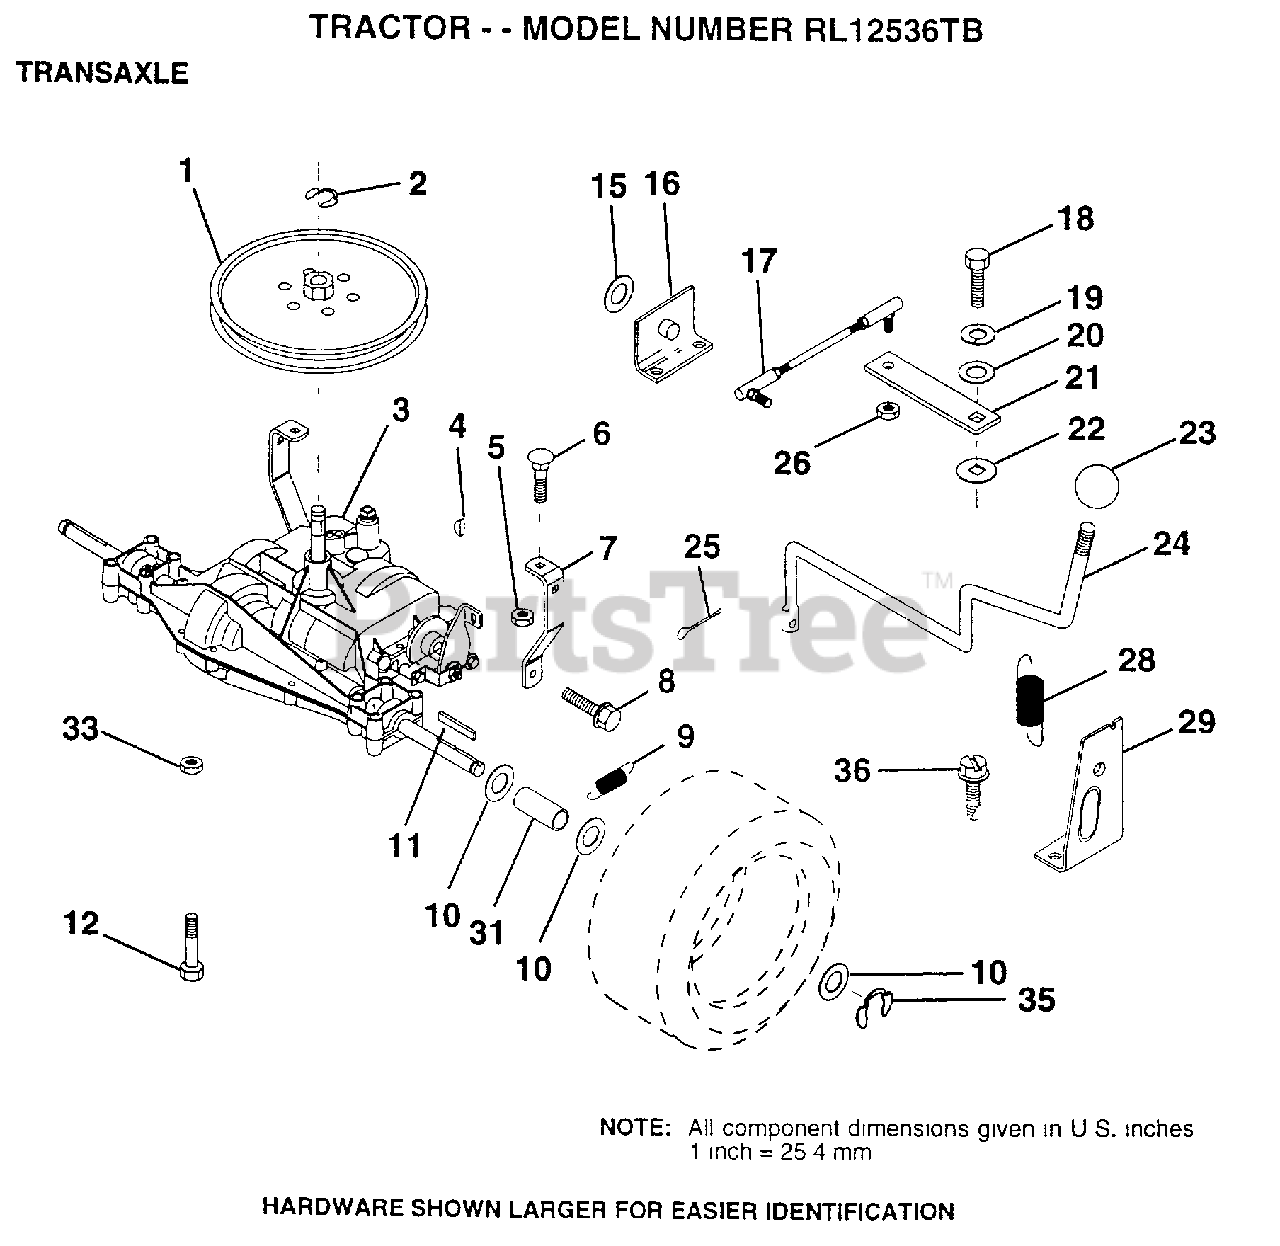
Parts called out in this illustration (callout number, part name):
1	PULLEY
6	BOLT
7	"STRAP,TORQUE"
8	SCREW
9	SPRING.BRAKE.RETU
10	WASHER
11	SQUARE KEY
12	BOLT
16	"SUPT,HDLE SHT LH"
17	"LINK,SHIFT"
18	BOLT.1/4-28.W/PAT
19	LOCKWASHER
20	WASHER LT
21	ARM SHIFT
22	WASH-SHFT PLT LT
23	KNOB T (1/2-HOLE)
24	"ROD,SHIFT"
25	PIN COTTER 1/8
26	NUT.LOCK.5/16-24
28	"SPRING,EXT"
29	"SUPT,HDLE RH"
31	SPACER LT
35	E-RING LT
36	SCREW
